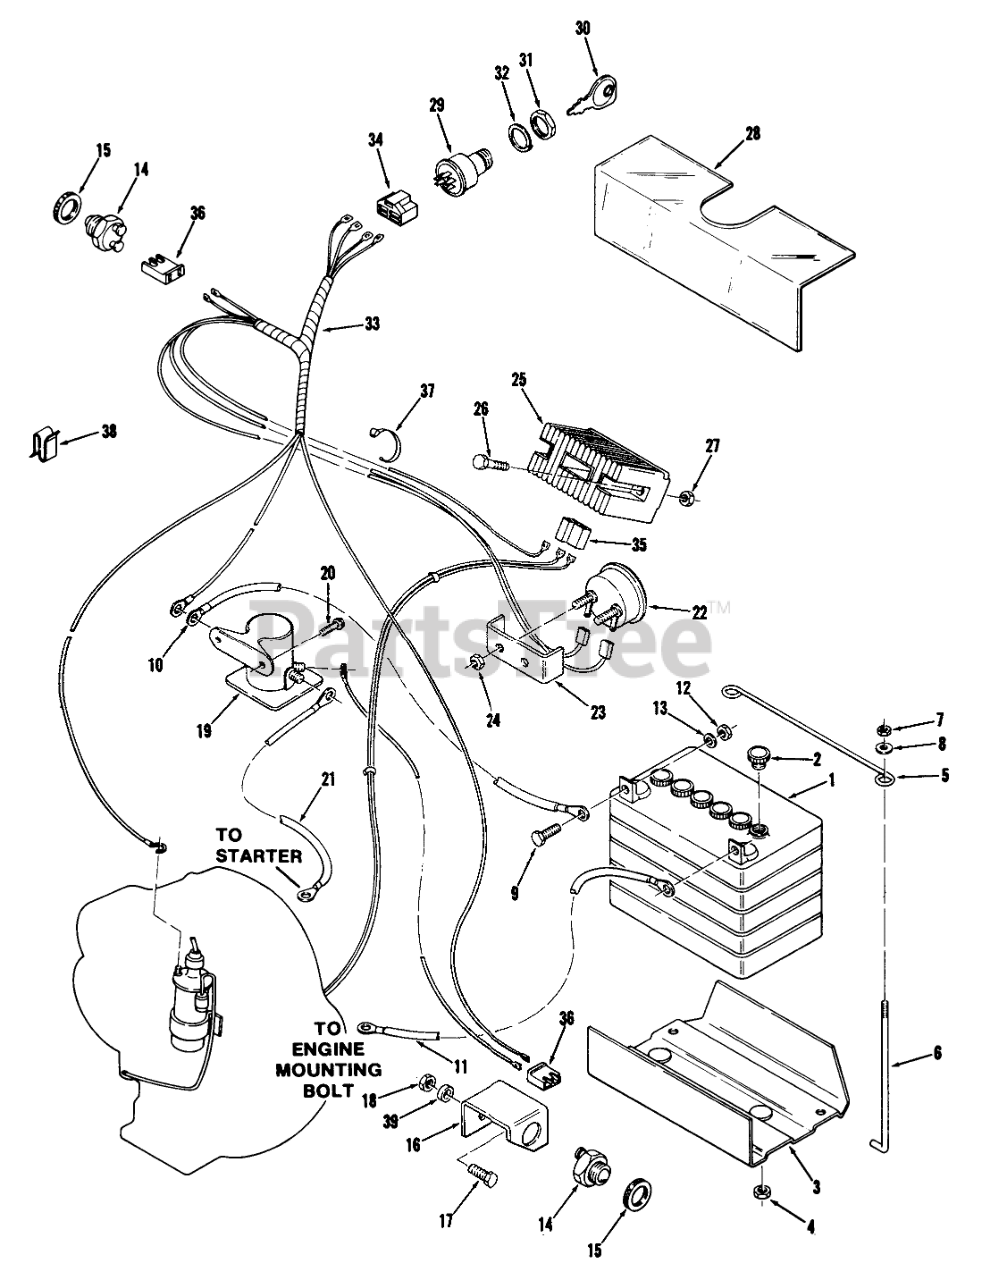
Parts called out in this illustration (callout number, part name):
1	Battery
3	Battery Box
4	Nut
5	ROD-HOLD DOWN
6	Hook
7	Nut
9	Bolt
10	Wire
11	Wire
12	Nut
14	SWITCH-INTERLOK CLUT
15	NUT-SPECIAL 9/16-18
16	Bracket
17	BOLT
18	Nut
19	Solenoid
20	Screw
21	Wire
22	AMMETER W/CLAMP
23	Clamp
24	HEX NUT 10-32 E.S.
25	REGULATOR-RECTIFIER
26	Bolt
27	Nut
28	CONTROL PROTECTOR
29	SWITCH-IGNITION
30	Key-EL
32	LOCKWASHER
33	WIRING HARNESS & DIA
34	CONNECTOR-5 WAY-SERV
35	CONNECTOR
36	Connector Housing Pedal Switch
37	PLASTIC TIE
38	SPEED CLIP
39	WASHER
